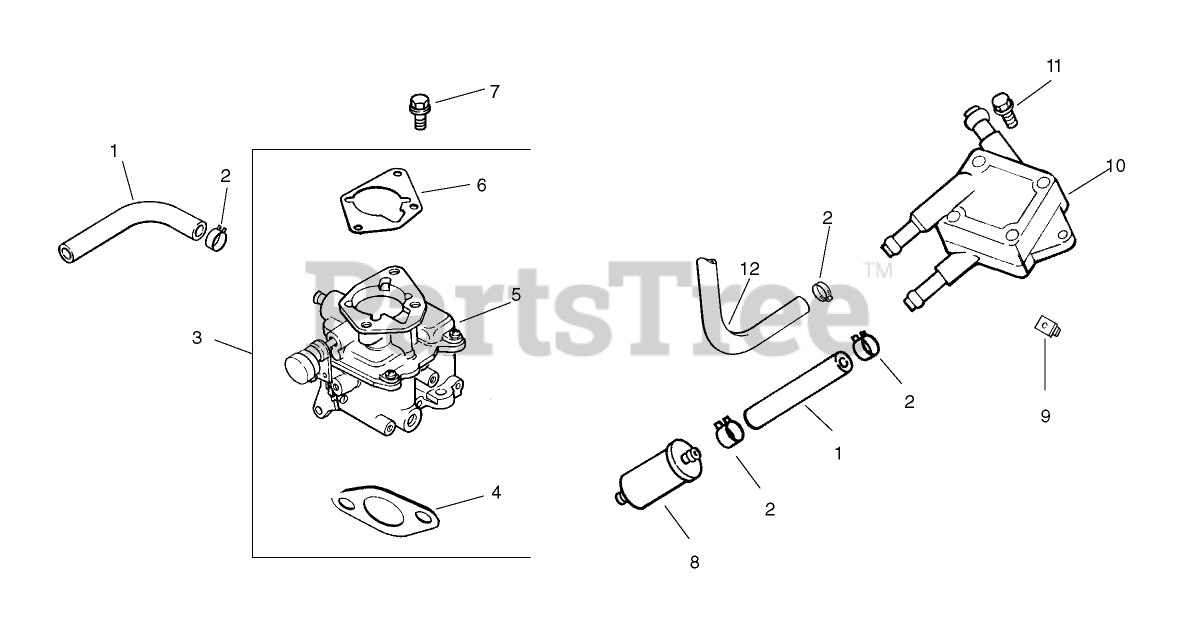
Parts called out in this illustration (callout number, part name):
1	Line-Fuel (9.5)
2	CLAMP-HOSE, SPRING (1/2)
3	Kit, carburetor w/gasket (Includes4-6)
4	GASKET-BASE, AIR CLEANER
5	Carburetor assembly (For information only not available seperately)(Includes 24 757 01-S, 24 757 02-S, 24 757 03-S, & 24 757 07-S,
6	Gasket-Carburetor
7	SCREW-FLANGE (M6X1.0X30)
8	Filter-Fuel
9	Nut-Plastic
10	PUMP-FUEL
11	SCREW-TAP (M6X1.7X18)
12	Line-Fuel, Flexible (15.5)
